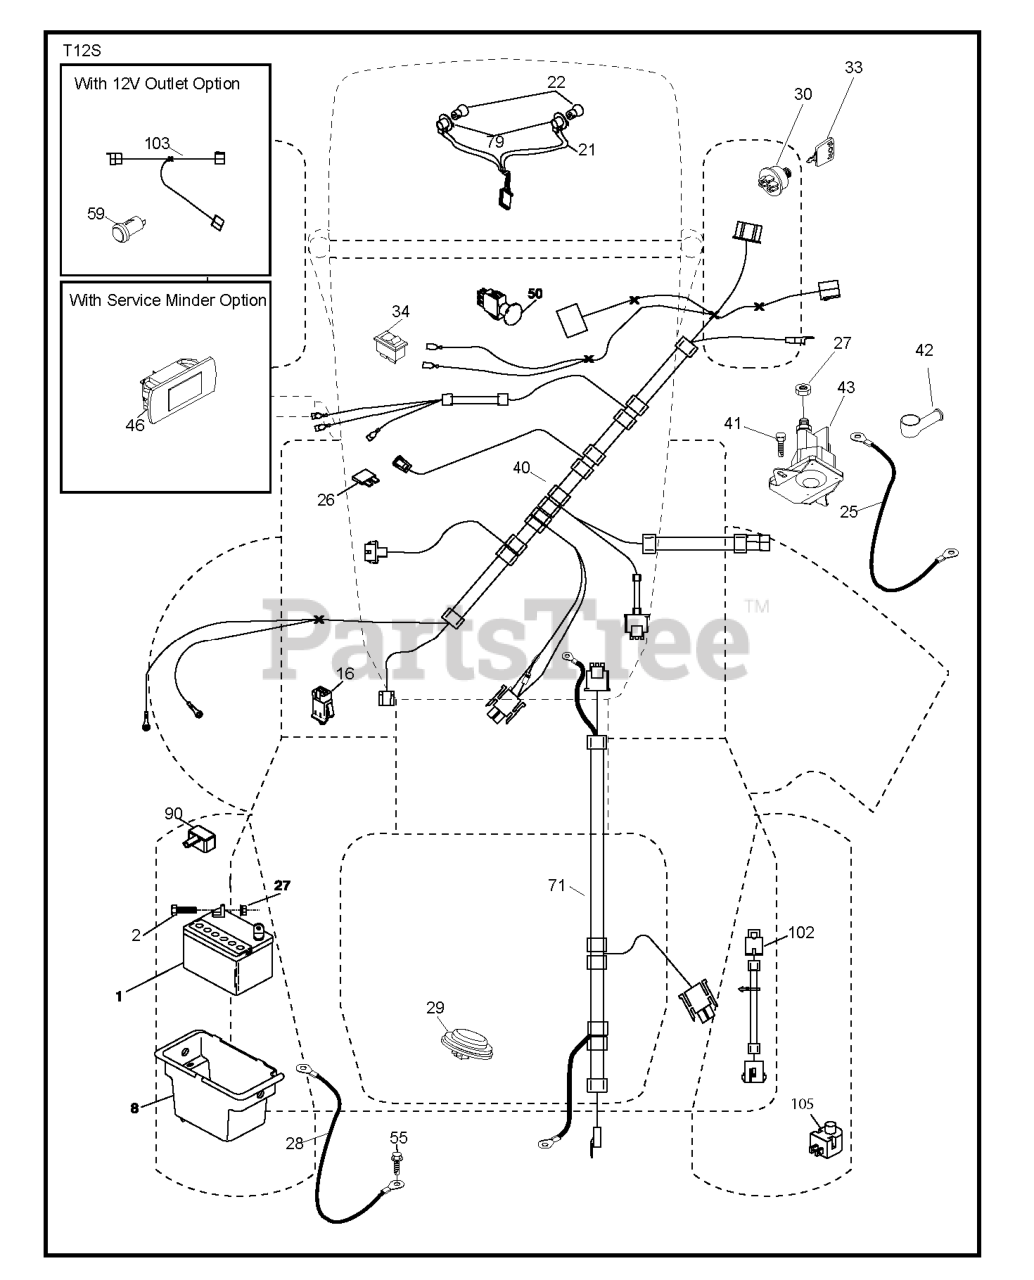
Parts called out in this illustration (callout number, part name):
1	Battery 12 Volt 25 Amp
2	BOLT.HEX.1/4.X.3/4.DICHROMATE
8	BOX.BATTERY.MNT.REAR.L
16	SWITCH INTERLOOK PUSH-IN
21	HARNESS.LIGHT W/4152J BULBS
25	CABLE.STARTER.6GA.BL/RED.14.
26	FUSE 20AMP
27	NUT
28	CABLE.BLACK.18"REAR.BA
29	SWITCH.SEAT.DELTA.OPC.
30	SWITCH.IGN.DELTA.W.LGH.ROS
33	KEY.CHAIN.BLISTER.PACK.GEN.USA
40	HARNESS.IGN.DASH.HUQ/P
41	SCREW
42	TERMINAL COVER
43	SOLENOID.W/BRASS.PLUNGER
46	RP.GUAGE.SRVCMNDR.HRMTR.
50	RP.PTO.SWITCH.8 TERMINAL.BLACK
55	SCREW 5/16"
71	HARNESS.IGN.CHASS.TEX.REAR.BAT
79	BULB HOLDER ASM.
90	COVER, TERMINAL BATTERY
102	HARNESS PIGTAIL PCH TEX ROS
105	REVERSE SWITCH
